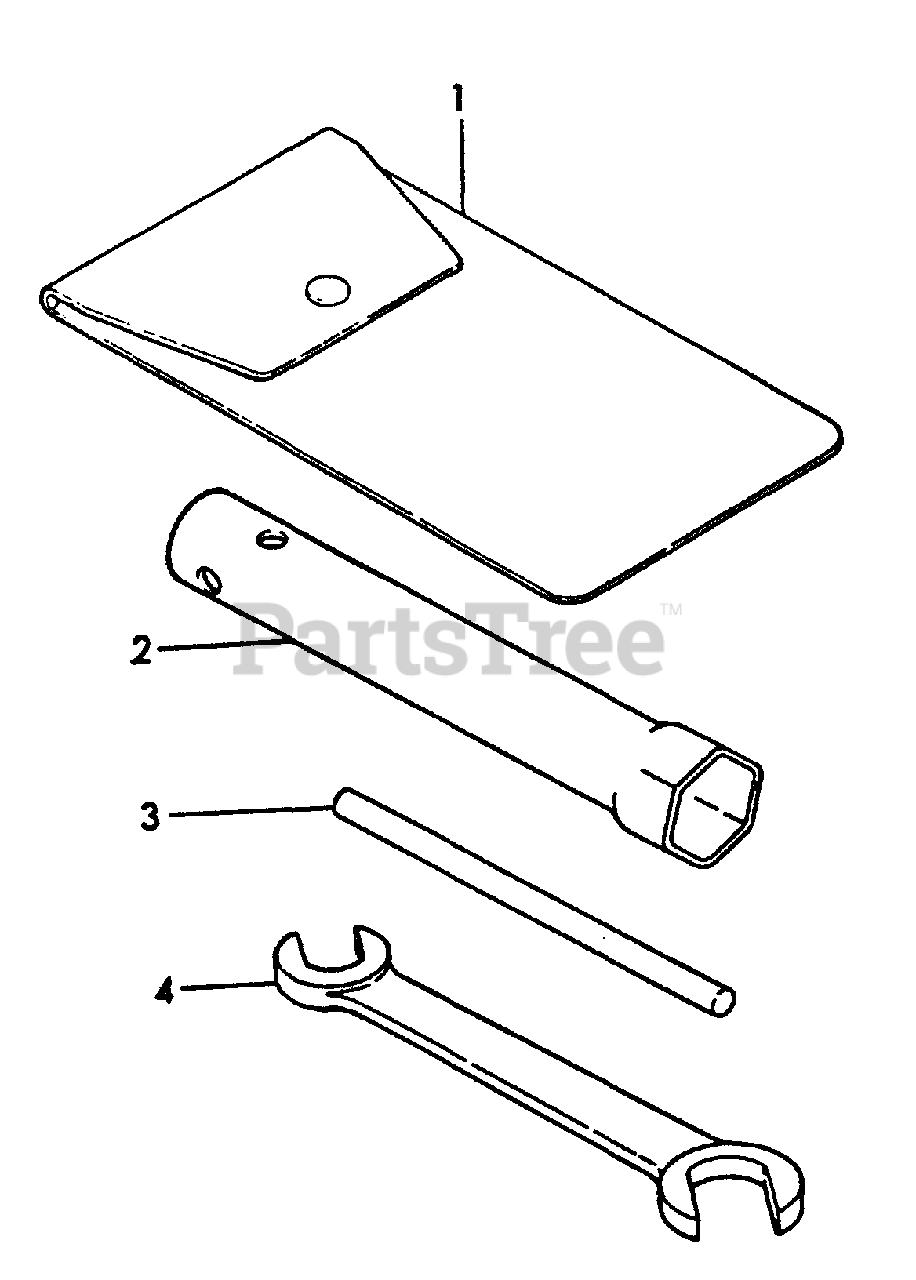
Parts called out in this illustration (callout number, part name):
1	BAG, TOOL
2	BOX WRENCH 21
3	BAR
4	WRENCH 10×12
